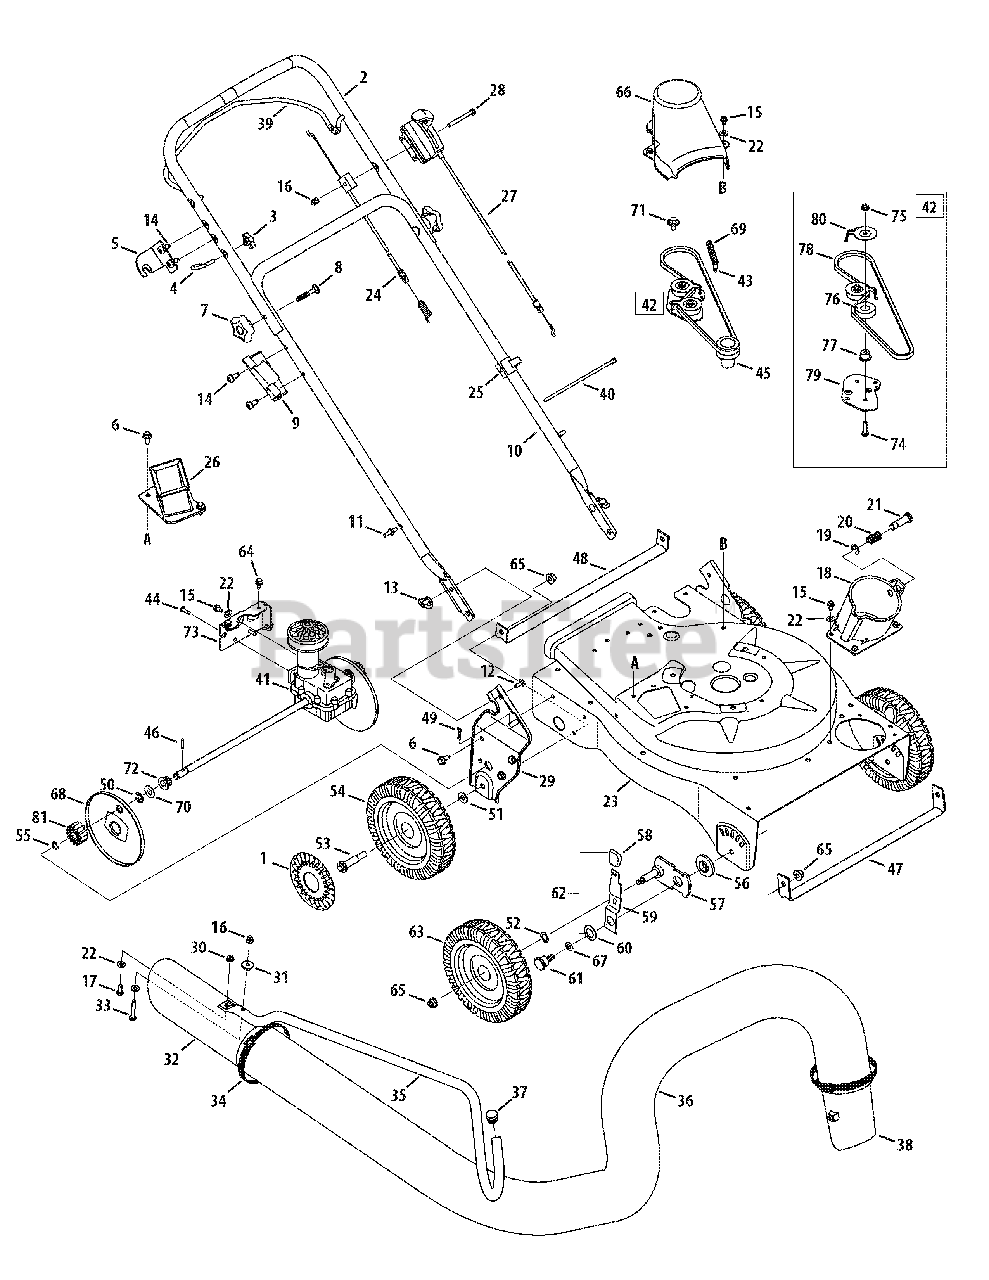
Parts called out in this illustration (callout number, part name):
1	Hub Cap
2	Upper Handle
4	Eye Bolt
5	Upper Handle Bracket
6	Hex Cap Screw 5/16-12 x.750
7	Handle Knob 5/16-18
8	Carriage Bolt
9	Nozzle Handle Clip
10	Lower Handle
11	Studs
12	Carriage Screw 1/4-20 x.75
13	Wing Nut 1/4-20
14	TT Screw, 5/16-18 x .750
15	Screw, 1/4-20 x .500
16	Cap Lock Nut, 1/4-20
17	Hex Cap Screw 1/4-20 x.620
18	Hose Base Adapter Assembly
19	E Ring.500 Dia
20	Compression Spring
21	Clevis Pin
22	Flat Washer.271 ID x.630 OD
23	Upper Flail Housing
24	Drive Control Cable
25	Cable Guide
26	Chipper Chute Assembly
27	Speed Control Cable
28	Hex Screw, 1/4-20 x 2.50
29	Handle Bracket Ass’y RH
30	Flange Lock Nut, 1/4-20
31	Spacer
32	Hose Nozzle
33	Hex Cap Screw 1/4-20 x 2.625
34	Adjustment Clamp
36	Vacuum Hose
37	Handle Plug
38	Hose Adapter
39	Drive Control
40	Cable Tie
41	Transmission Assembly
42	Idler Assembly
43	Shoulder Screw, #12-24 x .30 x .46
44	Screw, #12-16 x .750
45	Impeller Hub
46	Dowel Pin
47	Front Wheel Support Brace
48	Rear Wheel Support Brace
49	Cotter Pin
50	E-Ring
51	Flat Washer, .406 x .875 x .105
52	Wave Washer.531 ID x.781 OD
53	Shoulder Screw 3/8-16
54	Rear Wheel
55	Snap Ring
56	Height Adjustment Bearing
57	Pivot Arm Assembly
58	Height Adjustment Knob
59	Spring Lever
60	Bell Washer.760 ID x.25 OD
61	Shoulder Screw,.750 x.500
62	Height Lever Assembly
63	Front Wheel
64	Screw, 1/4-20 x .625
65	Flange Lock Nut, 3/8-16
66	Belt Cover
67	Thrust Washer.375 ID x.70 OD
68	Wheel Cover
69	Extension Spring,.375 x 2.95
70	Flat Washer,.508ID x1.00OD x.020
71	Shoulder Screw,.560 x.165
72	Drive Axle Bushing
73	Transmission Mounting Bracket
74	Screw, 1/4-20 x 1.00
75	Flange Lock Nut, 1/4-20
76	Ball Bearing
77	Flange Spacer,.260 x.659 x.517
78	Belt, 3/8 x 32.5
79	Idler Bracket
80	Belt Keeper
81	Spur Gear - RH
